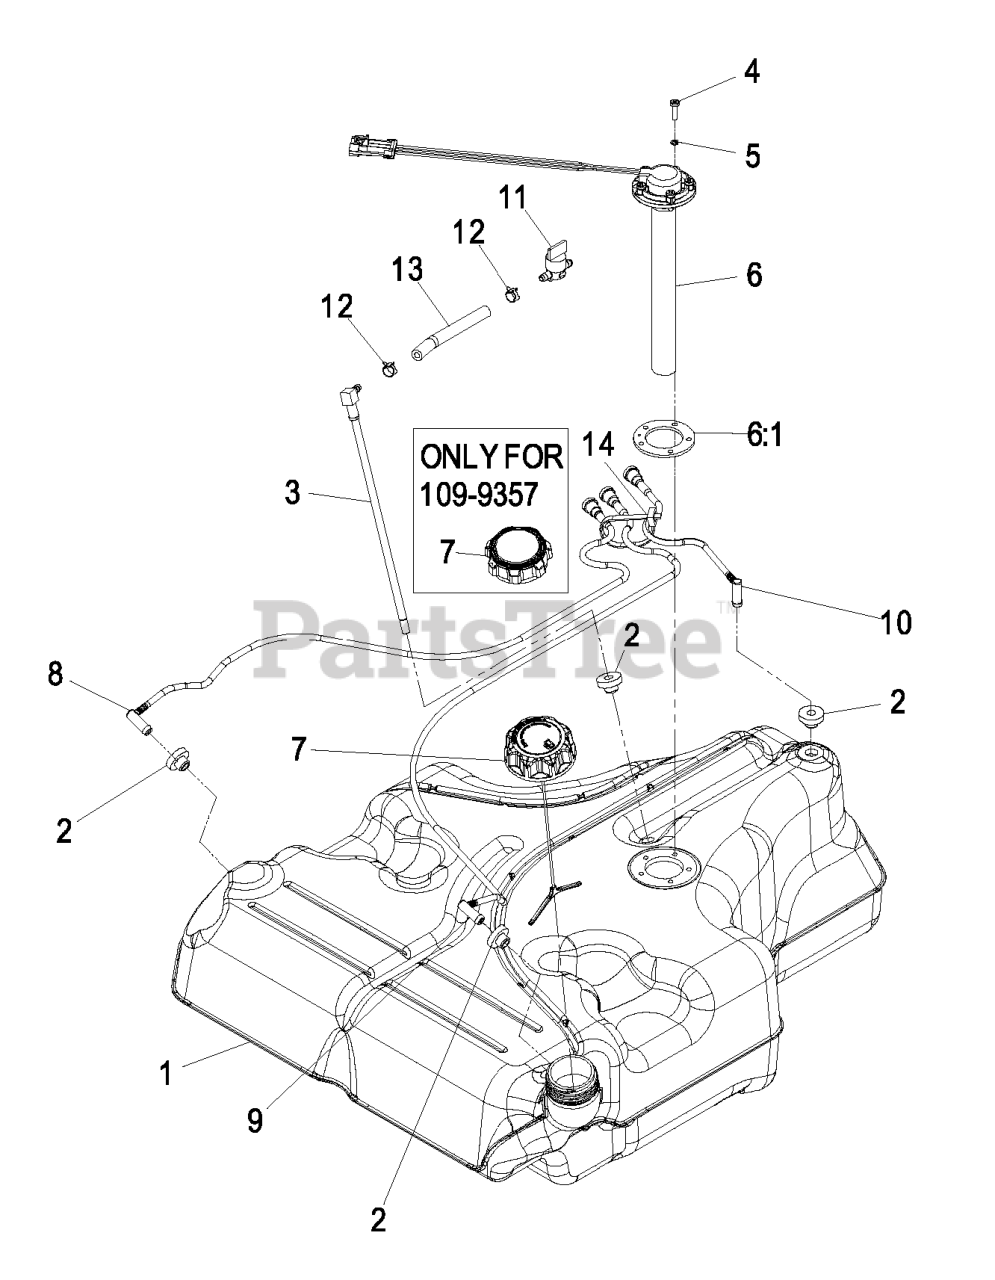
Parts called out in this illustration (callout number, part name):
2	BUSHING
3	FUEL LINE KIT (WITH GROMMET)
4	SCREW-PAN
5	WASHER-LOCK
6:1	GASKET-SENDER, FUEL
8	RH VENT LINE KIT (WITH GROMMET)
9	LH VENT LINE KIT (WITH GROMMET)
10	REAR VENT LINE KIT (WITH GROMMET)
11	VALVE-FUEL
12	CLAMP-HOSE
13	HOSE-FUEL
14	TIE-PLASTIC
